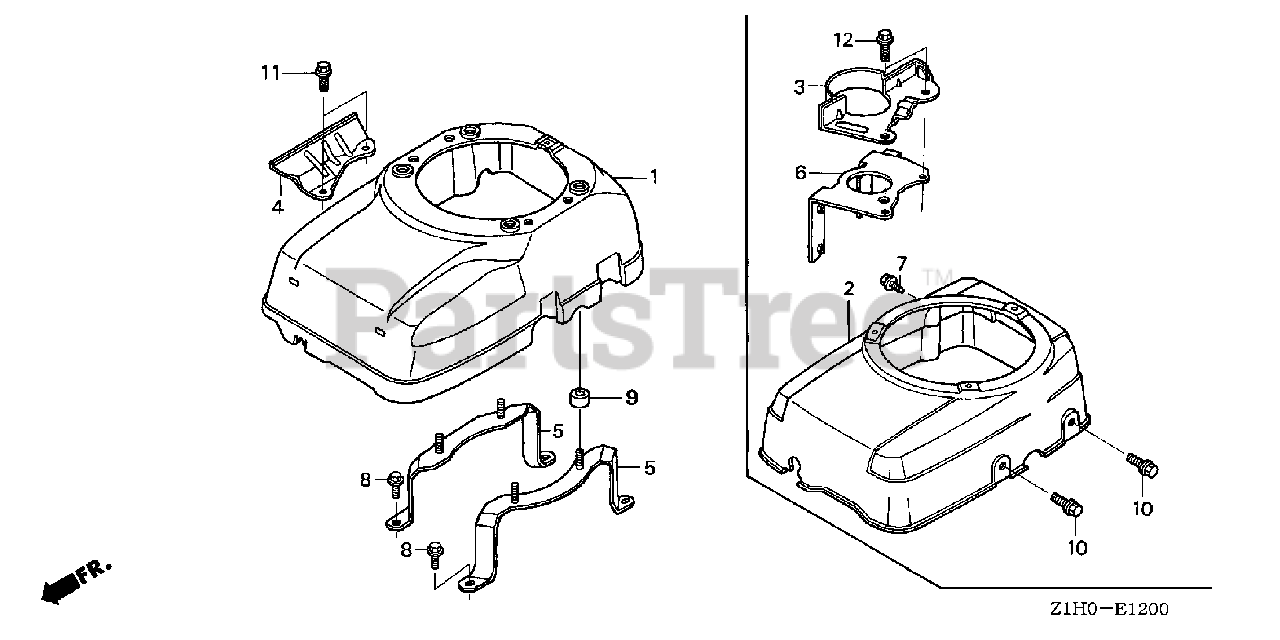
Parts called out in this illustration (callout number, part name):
1	COVER, FAN *R280* (POWER RED)
4	PLATE, SIDE
5	BRACKET, FAN COVER
8	BOLT, FLANGE (6X16) (CT200)
9	COLLAR, FAN COVER
11	BOLT, FLANGE (8X20)
